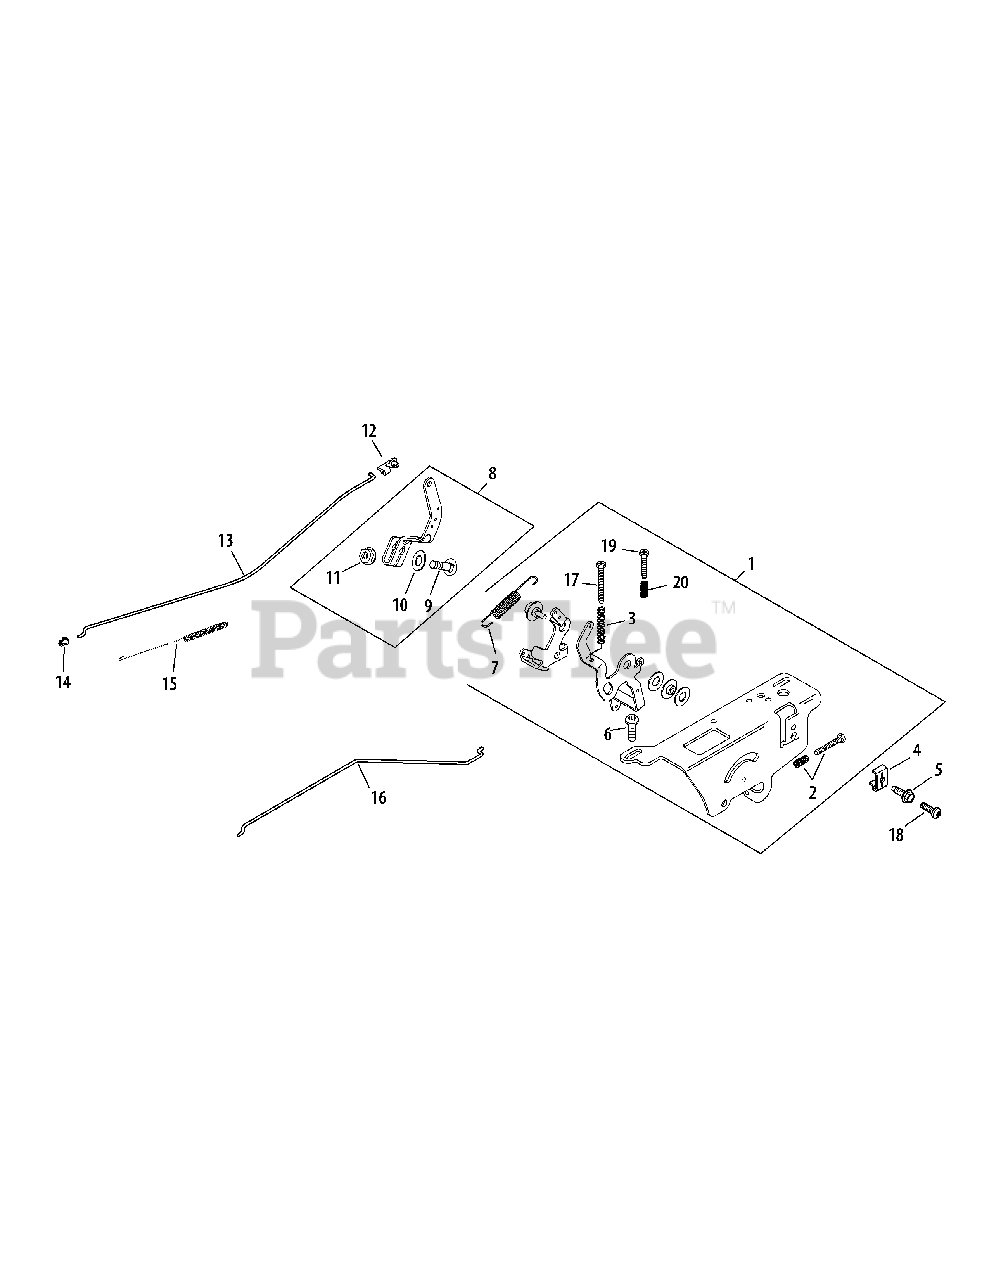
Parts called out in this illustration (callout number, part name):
1	Speed Control Assembly Kit
2	Idle Adj. Screw & Spring Kit
3	Spring Speed Control (Long)
4	Cable Clamp
5	Flg. Thd. Frm. Screw, M5 X 0.8 X 16
6	Lbd. Skt. Screw, M6 X 1.0 X 20
7	Governor Spring
8	Governor Ass’y Lever (Inc. 9-11)
9	Rd. Hd. Sq. Nck. Bolt, 1/4-20 X 1
10	Int. Tooth Lock Washer, 1/4
11	Hex Flg Nut, 1/4-20
12	Throttle Linkage Bushing
13	Throttle Linkage
14	Linkage Retaining Bushing
15	Linkage Spring
16	Choke Linkage
17	Phl. Thd. Frm. Screw, M4 X 0.7 X 38
18	Not used in this application
19	Phl. Thd. Frm. Screw, M4 X 0.7 X 25
20	Speed Control Spring (Short)
